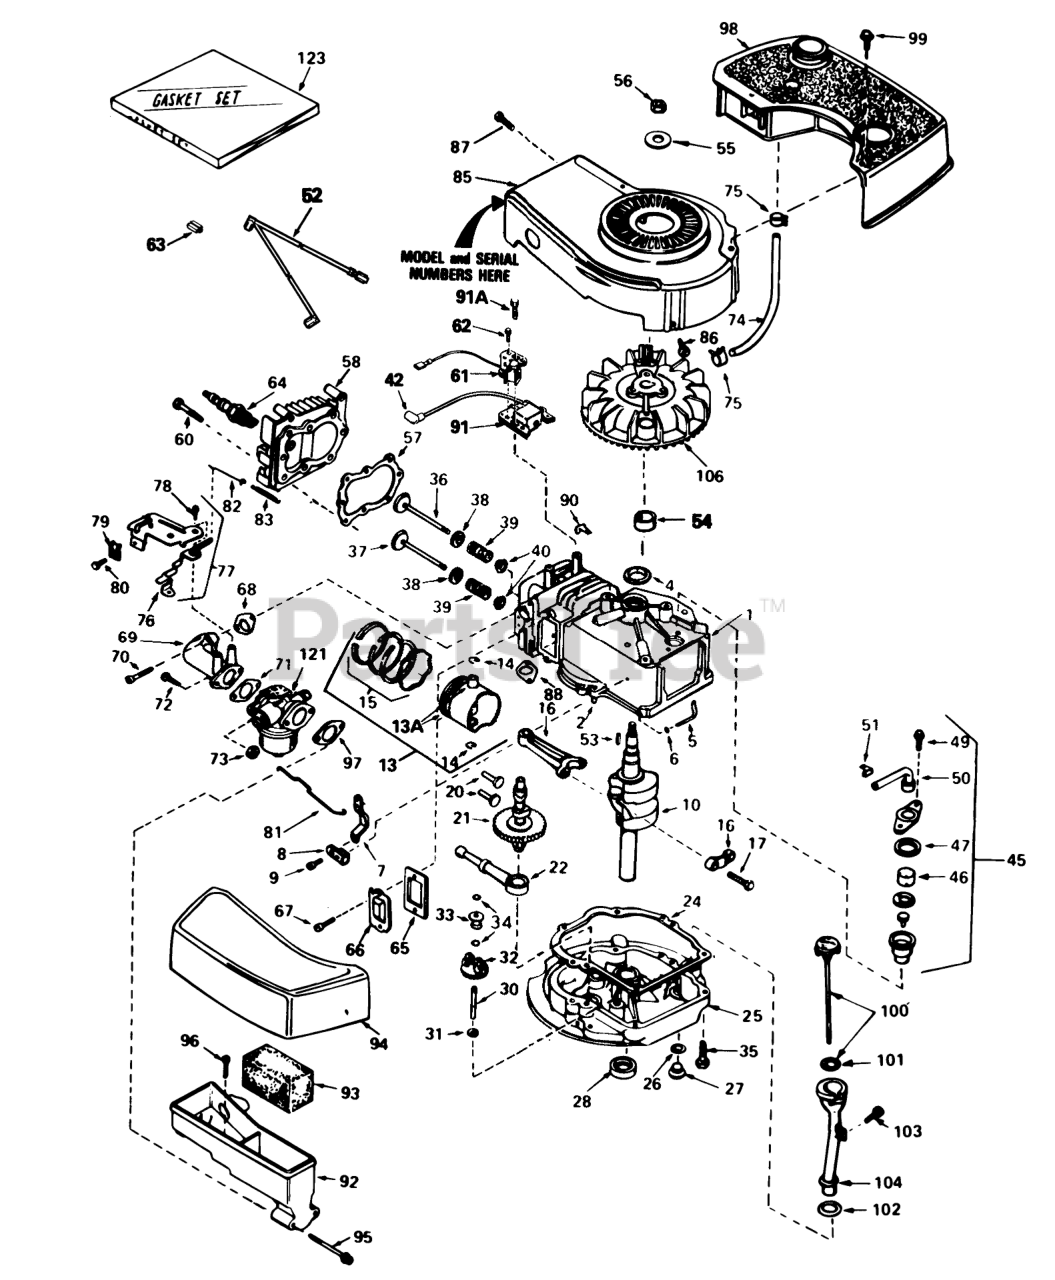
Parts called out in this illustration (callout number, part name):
1	Cylinder Assy (Incl. #2 & 4)
2	Pin-Dowel
4	Seal-Oil
5	Rod, Governor (Incl. #6)
6	Washer-Flat
7	Governor Lever
8	Clamp-Lever, Governor
9	Screw
10	Crankshaft
13	Piston, Pin & Ring Assy. (Std.) (Incl. #13A, 14 & 15)
13	Piston, Pin 8 Ring Assy. (.010 oversize) (Incl. #13A, 14 & 15)
13	Piston, Pin & Ring Assy. (.020 oversize) (Incl. #13A, 14 & 15)
13A	Piston & Pin Assy. (Std.) (Incl. #14)
13A	Piston & Pin Assy. (.010 over size) (Incl. #14)
13A	Piston & Pin Assy. (.020 Oversize) (Incl. #14)
14	Ring-Retaining, Piston Pin
15	Ring Set (Std.)
15	Ring Set (.020" OS)
15	Ring Set (.010" OS)
16	Rod Assy., Connecting (Incl. #17)
17	Bolt-Rod, Connecting
20	Lifter-Valve
21	Camshaft(Mech.Comp. Release)
22	Oil Pump ASM
24	Gasket, Mounting
25	Flange Assy., Mounting (Incl. #26 thru 30)
26	Gasket-Oil Drain
27	Plug Oil Drain
28	Seal Oil
30	Shaft-Governor
31	Washer-Flat
32	Gear Assy., Governor (Incl. #31)
33	Spool-Governor
34	Ring-Retaining
35	Screw (1/4-20 x 1-1/4)
36	Valve, Intake (Std.) (Incl. #40)
36	Valve, Intake (1/32" oversize) (Incl. #40)
37	Valve, Exhaust (Std.) (Incl. #40)
37	Valve, Exhaust (1/32" oversize) (Incl. #40)
38	Cap-Upper Valve Spring
39	Spring-Valve
40	Cap-Valve, Spring
42	Cover-Spark Plug
45	Breather Assy. (Incl. #46 thru 51)
46	Element-Breather
47	Gasket-Breather
49	Screw (10-24 x 9/16)
50	Tube, Breaker
51	Clip, Breather
52	Wire-Ground
53	Key-Flywheel
55	Washer-Belleville
56	Nut-Flywheel
57	63573 GIL 42 SNWTHW
58	Head-Cylinder
60	Screw (5/16-18x1-1/2)
61	Coil, Alternator
62	Screw (8-32x27/64)
63	Connector-Body
64	Plug, Spark (J17LM or equiv.)
64	Plug, Spark (Champion RCJ-8)
65	Gasket-Breather
66	Cover-Valve
68	Gasket-Intake
69	Pipe, Intake (Incl. No. 68)
70	Screw (1/4-20 x 1)
71	Gasket-Carburetor
72	Screw (1/4-28 x 7/8)
73	Nut and Lock Washer (1/4-28)
74	Line-Fuel
75	Clamp-Line, Fuel
76	Lever Control
77	Control Assy., Speed (Incl. #76 & 78)
78	Screw, Hex Washer Hd Shoulder Self-Tap
79	Conduit
80	Screw (10-32 x 3/8)
81	Link-Throttle
82	Link Governor Spring
83	Spring Governor
85	Housing-Blower
86	Screw (1/4-20x19/32)
87	Screw (10-24 x 9/16)
88	Gasket Exhaust
90	Clip-Wire
91	Lamination & Coil Assy. (Solid State) (Incl. #42)
91A	Screw
92	Body Air Cleaner
93	Filer, Air
94	Cove, Air Cleaner
95	Screw Fil Hd.
96	Screw, Hex Hd.
97	Gasket-Air Cleaner
98	Tank-Fuel
99	Screw (10-32 x 35/64)
100	Dipstick, Oil (Incl. #101)
103	Screw (10-32 x 1/2)
104	Tube-Oil Fill
106	Flywheel
121	Carburetor (Incl. #71)
123	Gasket Set (Incl. items marked )
